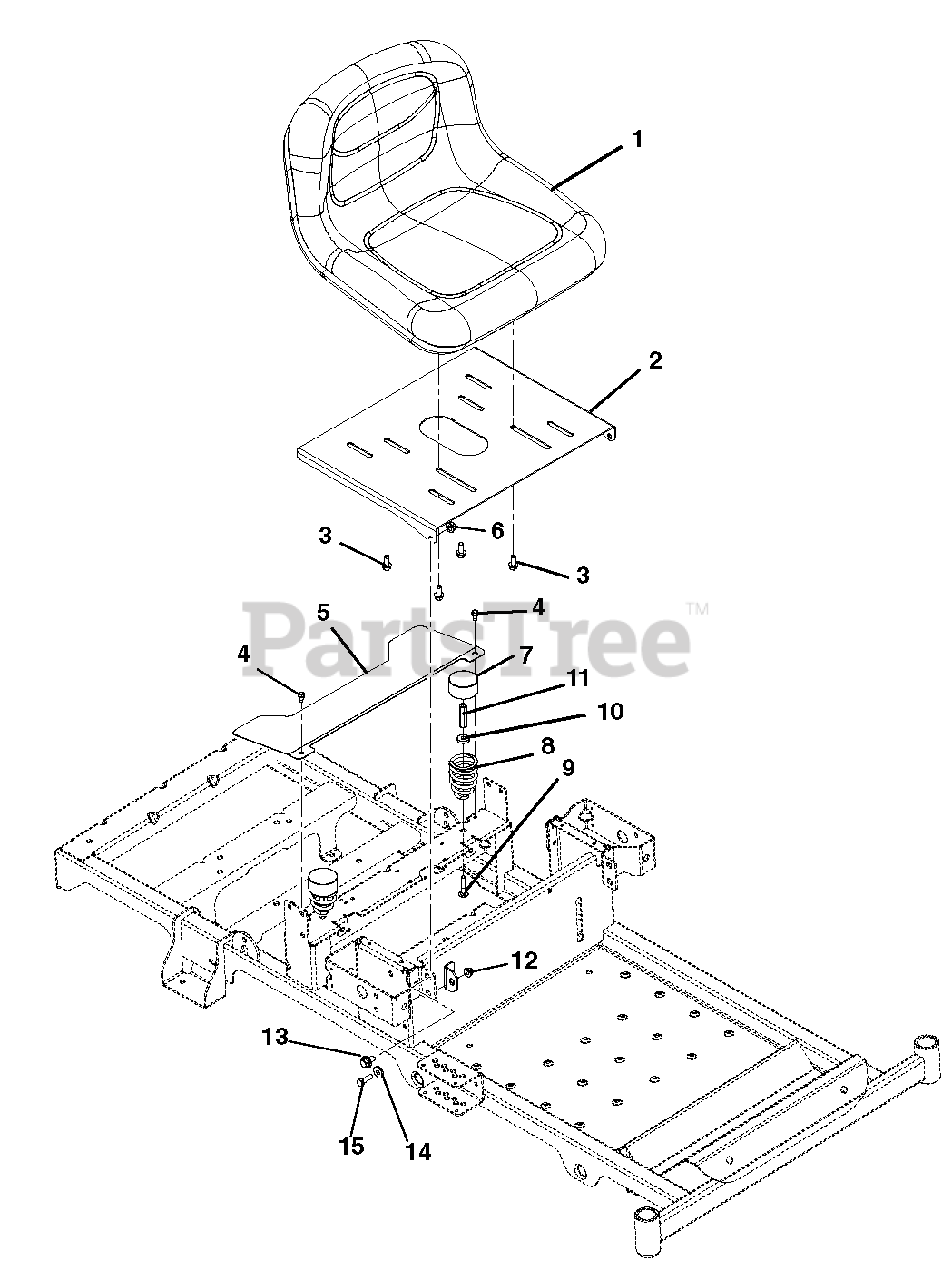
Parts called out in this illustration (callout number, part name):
1	Seat, 13 in Grey (140, 142)
2	Seat Plate
3	Bolt, Hex 5/16-18 x 3/4
4	Screw, Tapping .25-20 x .50 Hex Washer Head Thread
5	Guard, Fan
6	Nut, .38-16 Locking Top Flange
8	Spring, Seat
9	Bolt, Round Head Square Neck .31-18 x 1.50 Grade 5
10	Washer-Flat-Steel .328 x .87 x .179
11	Nut, Coupling 5/16-18 x 1 .75
12	Nut, 5/16-18 Flange Nyloc
13	Bolt, Shoulder .375-16 x .135
14	Bushing, Flange .325 x .499 x .26 x .88
15	Bolt, Hex .31-18 x 1.00 Grade 5
